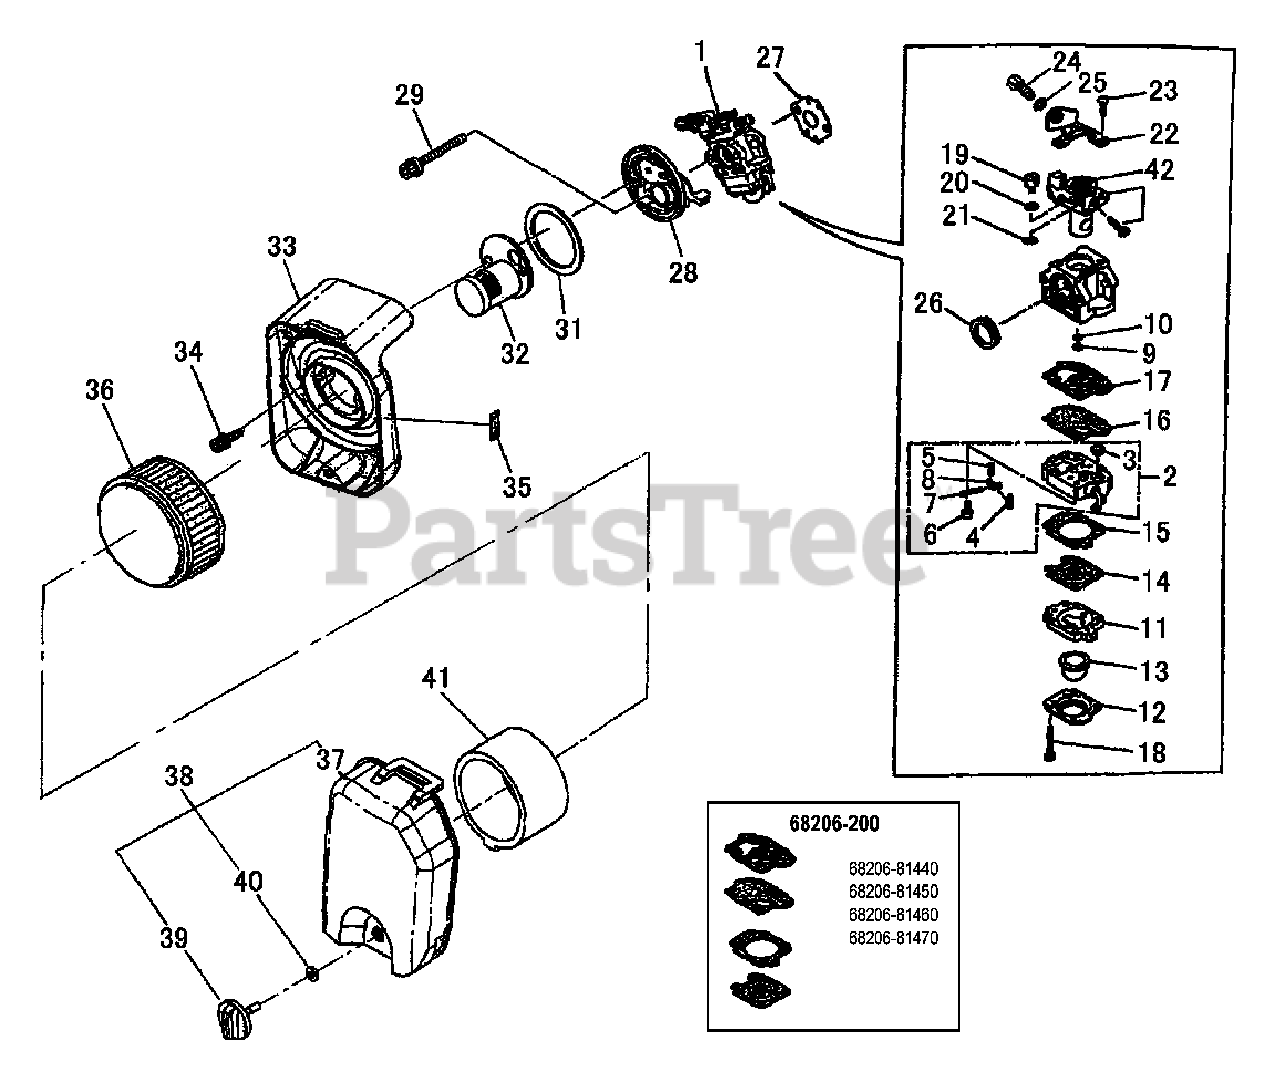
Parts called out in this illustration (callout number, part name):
1	CARBURETOR
2	BASE, PURGE
3	STRAINER
4	VALVE, NEEDLE
5	SPRING, METERING LEVER
6	SCREW, METERING LEVER PIN
7	PIN, METERING LEVER
8	LEVER, METERING
9	JET, MAIN
11	BASE, PURGE
12	COVER, PUMP
13	BULB, PURGE
14	DIAPHRAGM, METERING
15	GASKET, METERING
16	DIAPHRAGM, PUMP
17	GASKET, PUMP
21	RING, RETAINING
22	BRACKET, CABLE
24	NUT, CABLE ADJUST
26	SEAL
27	GASKET, INTAKE
28	CHOKE ASSY
29	SCREW - 5X50
31	GASKET
32	ADAPTOR, INTAKE
33	CASE, AIR FILTER
34	SCREW - 4X14
35	LABEL - CHOKE
36	FILTER, AIR
37	COVER, AIR FILTER - BLACK
38	AIR FILTER COVER ASSY
39	THUMBSCREW
40	WASHER - VINYL
41	PRE-FILTER
42	THROTTLE VALVE ASSY
68206-200	GASKET/DIAPHRAGM KIT
68206-81440	DIAPHRAGM
68206-81460	DIAPHRAGM
68206-81470	GASKET, PUMP
